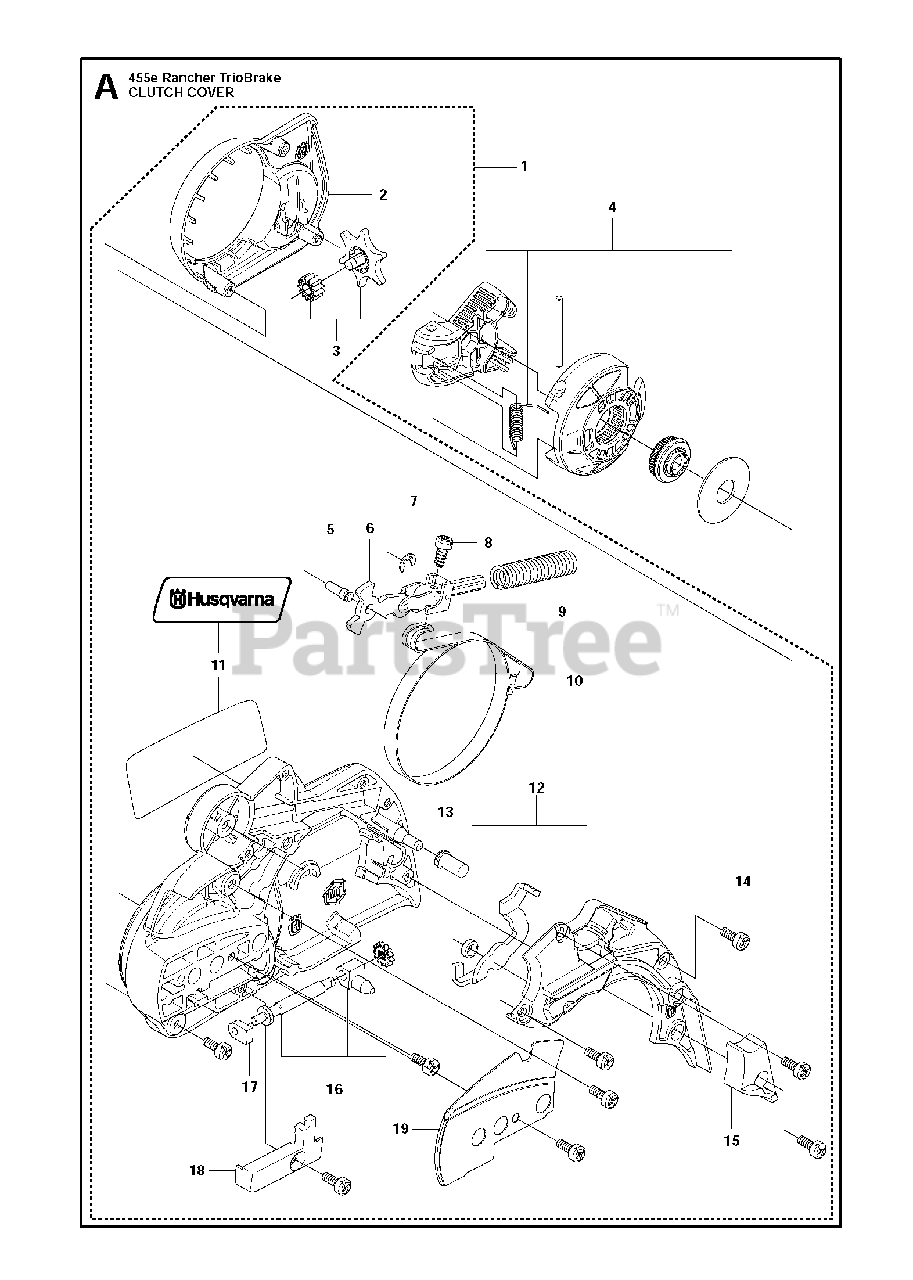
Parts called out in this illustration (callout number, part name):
1	CLUTCH COVER ASSY
2	HEAT SHIELD
3	CHAIN TENSIONER WHEEL, COMP.
4	KNOB, COMPLETE
5	PIN
6	JOINT
7	E-RING 4
8	SCREW
9	SPRING
10	BRAKE BAND
11	DECAL, CLUTCH HOUSING
12	COVER LID ASSY
13	SLEEVE
14	SCREW
15	WEAR GUARD, CHAIN
16	CHAIN TENSIONER SCREW, COMP.
17	RP BEARING SLEEVE
18	COVER
19	PLATE
